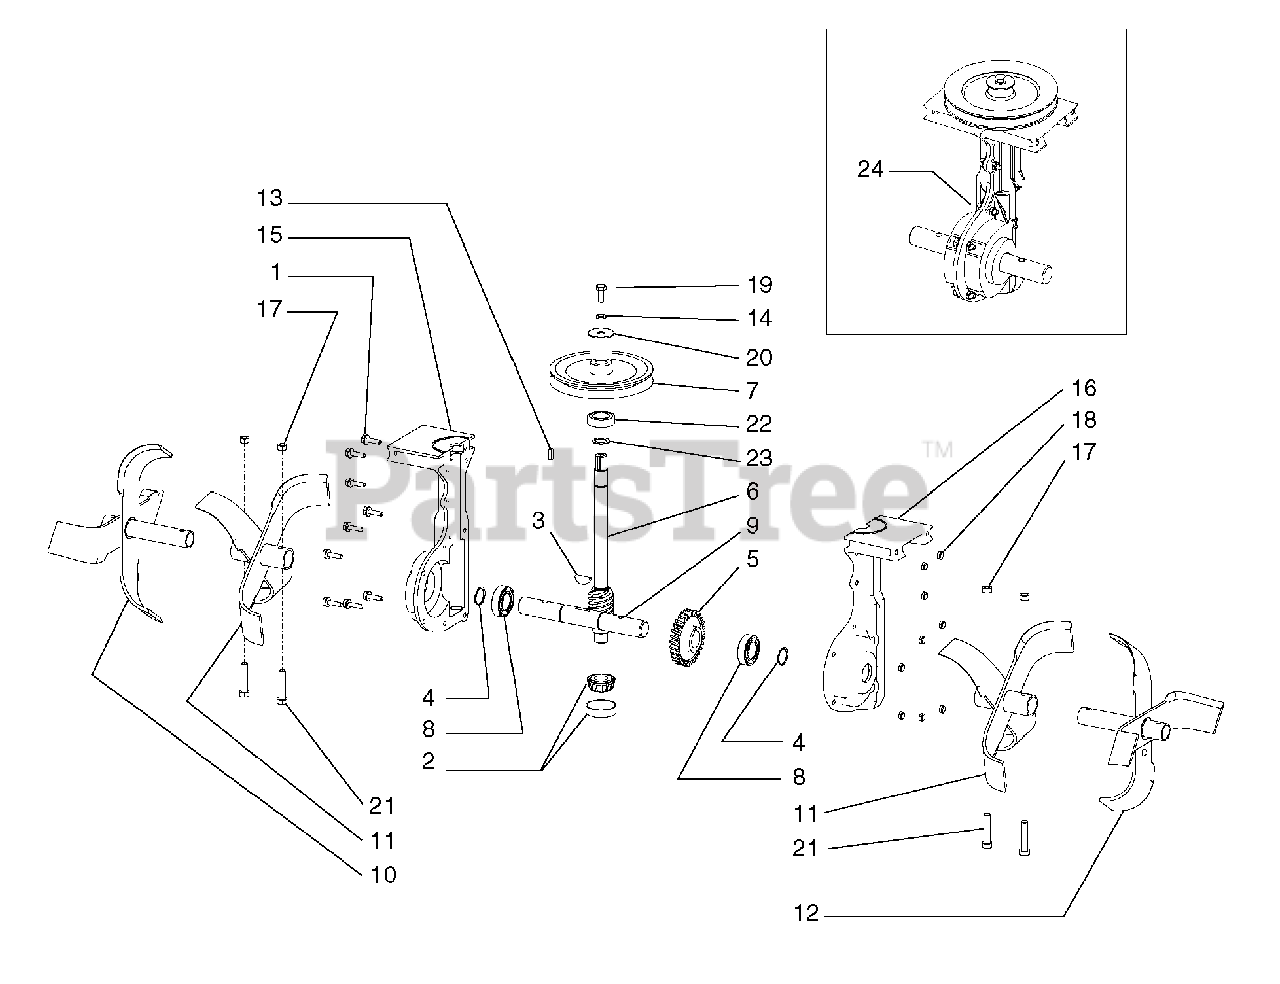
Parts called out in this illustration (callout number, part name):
1	BOLT, Serated-Flange, Hex-Head, 1/4-20 x 7/8
2	BEARING, Tapered (Includes Cone & Race)
3	KEY, Half-Moon, 1/4 x 1
4	RING, Snap, External
5	* GEAR , Brass, 1" I.D.
6	* SHAFT, Drive
7	PULLEY, Single-Groove
8	BEARING, Sealed, 1" I.D. (replaces 3205 bearing & 747 spacer)
10	TINE SET, Outside, Right
11	TINE SET, Inside
12	TINE SET, Outside, Left
13	KEY, Square, 3/16 x 5/8
14	LOCKWASHER, Spring, 5/16
15	* CASTING, Right Side
16	* CASTING, Left Side
17	NUT, Bi-Way Lock, 5/16-18
18	NUT, Hex Ny-Lock, 1/4-20
19	SCREW, Hex-Head, 5/16-24 x 3/4
20	WASHER, 5/16 I.D. x 1-5/8 O.D.
21	BOLT, Hex-Head, 5/16-18 x 1-3/4
22	BEARING, Ball, R12
23	RING, Snap, External, 3/4
24	TRANSMISSION, Complete
